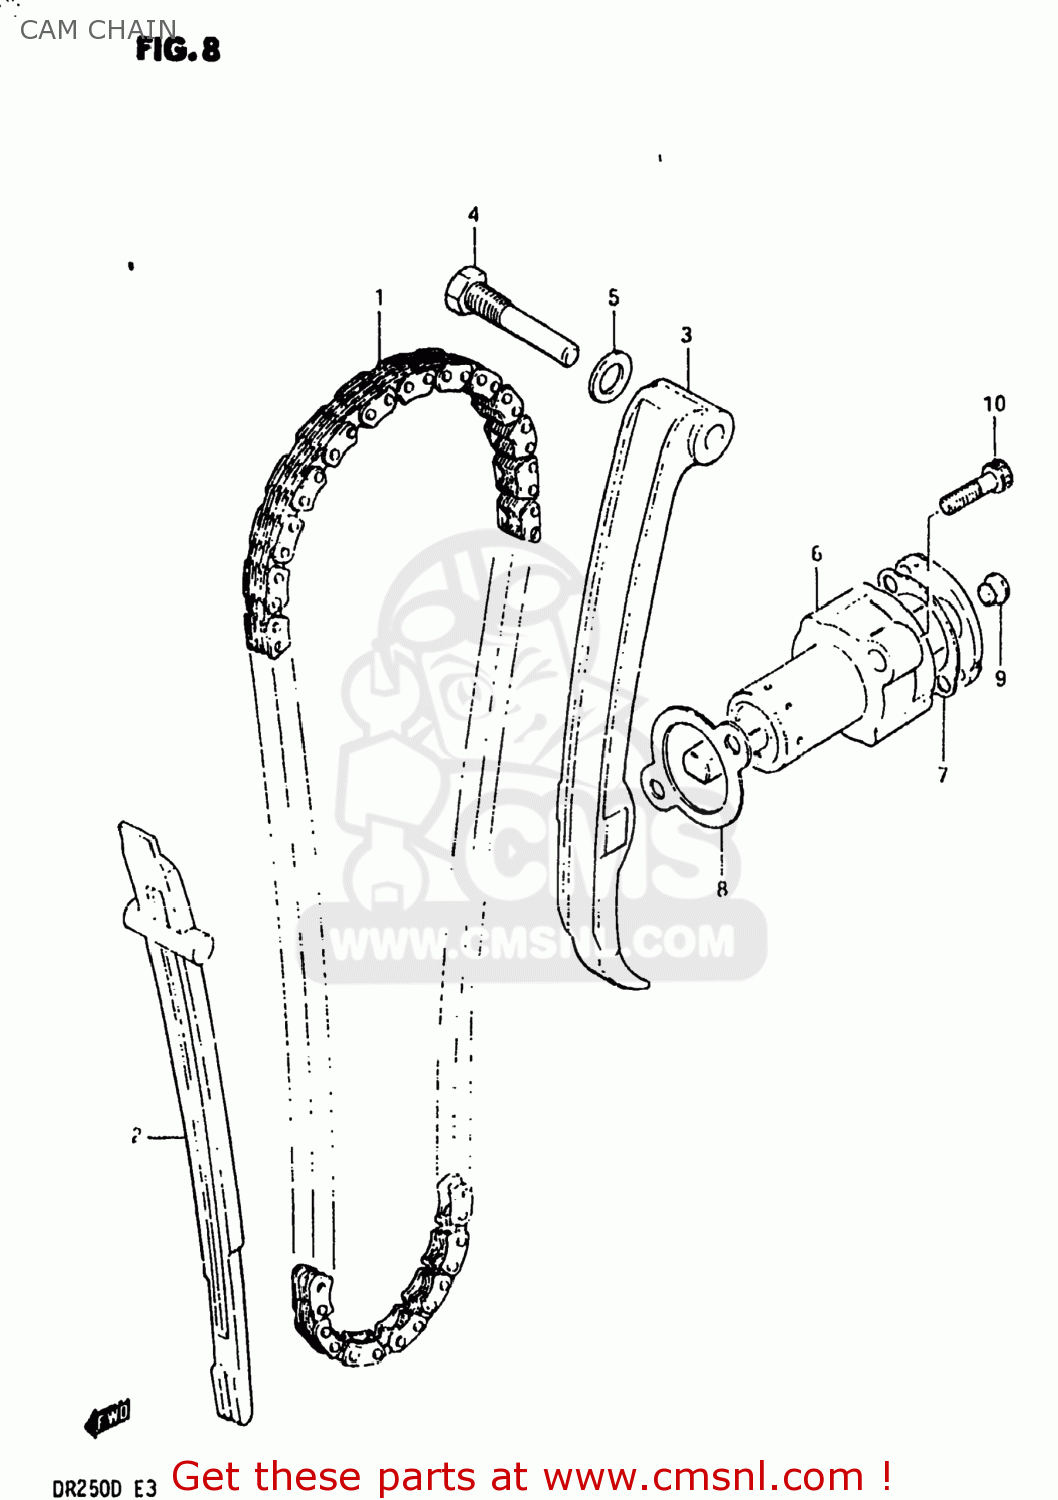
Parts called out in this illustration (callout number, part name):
1	CHAIN,CAMSHAFT DRIVE
2	GUIDE,CAM CHAIN
3	TENSIONER,CAM CHAIN
4	BOLT,CAM CHAIN TENSIONER
5	GASKET 8.2X14X1 (NAS)
6	ADJUSTER ASSEMBLY,TENSIONER
7	GASKET,ADJUSTER CAP (MCA)
8	GASKET,TENSIONER ADJUSTER (MCA)
9	PLUG,ADJUSTER
10	BOLT
